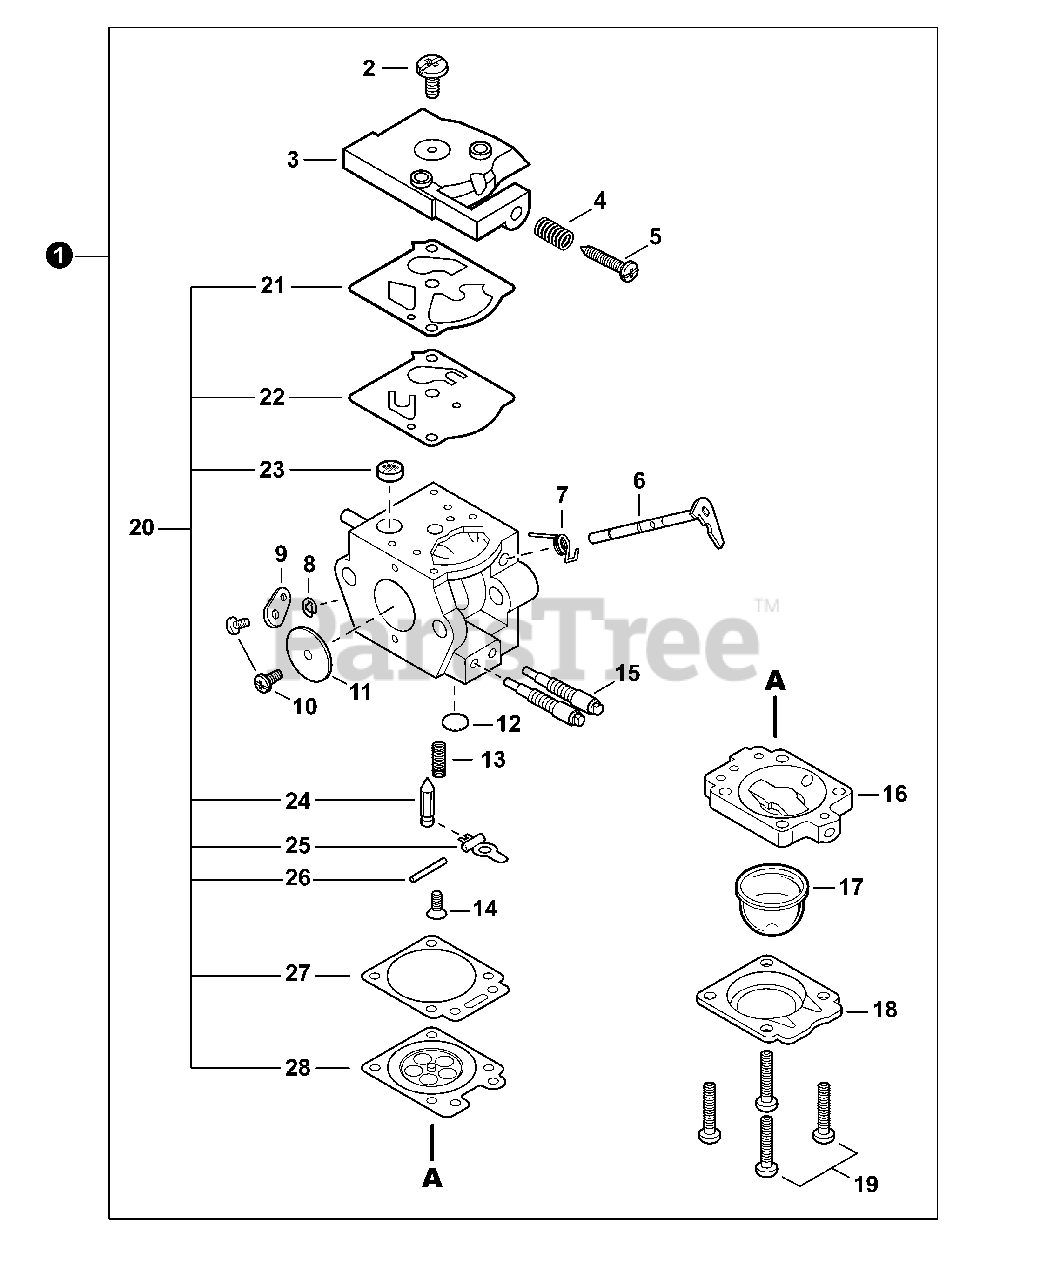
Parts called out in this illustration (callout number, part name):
1	CARBURETOR WTA-35
3	COVER, FUEL PUMP
4	SPRING, IDLE ADJUST
5	SCREW, IDLE ADJUST
6	SHAFT, THROTTLE
9	LEVER, THROTTLE
11	VALVE, THROTTLE
12	PLUG, WELCH
13	SPRING, METERING LEVER
16	BODY ASSY, PURGE
17	BULB, PURGE
18	RETAINER, PURGE BULB
20	REPAIR KIT, CARBURETOR
21	GASKET, PUMP
22	DIAPHRAGM, PUMP
23	SCREEN, INLET
24	VALVE, INLET NEEDLE
25	LEVER, METERING
26	PIN, METERING LEVER
27	GASKET, METERING DIAPHRAGM
28	DIAPHRAGM, METERING
